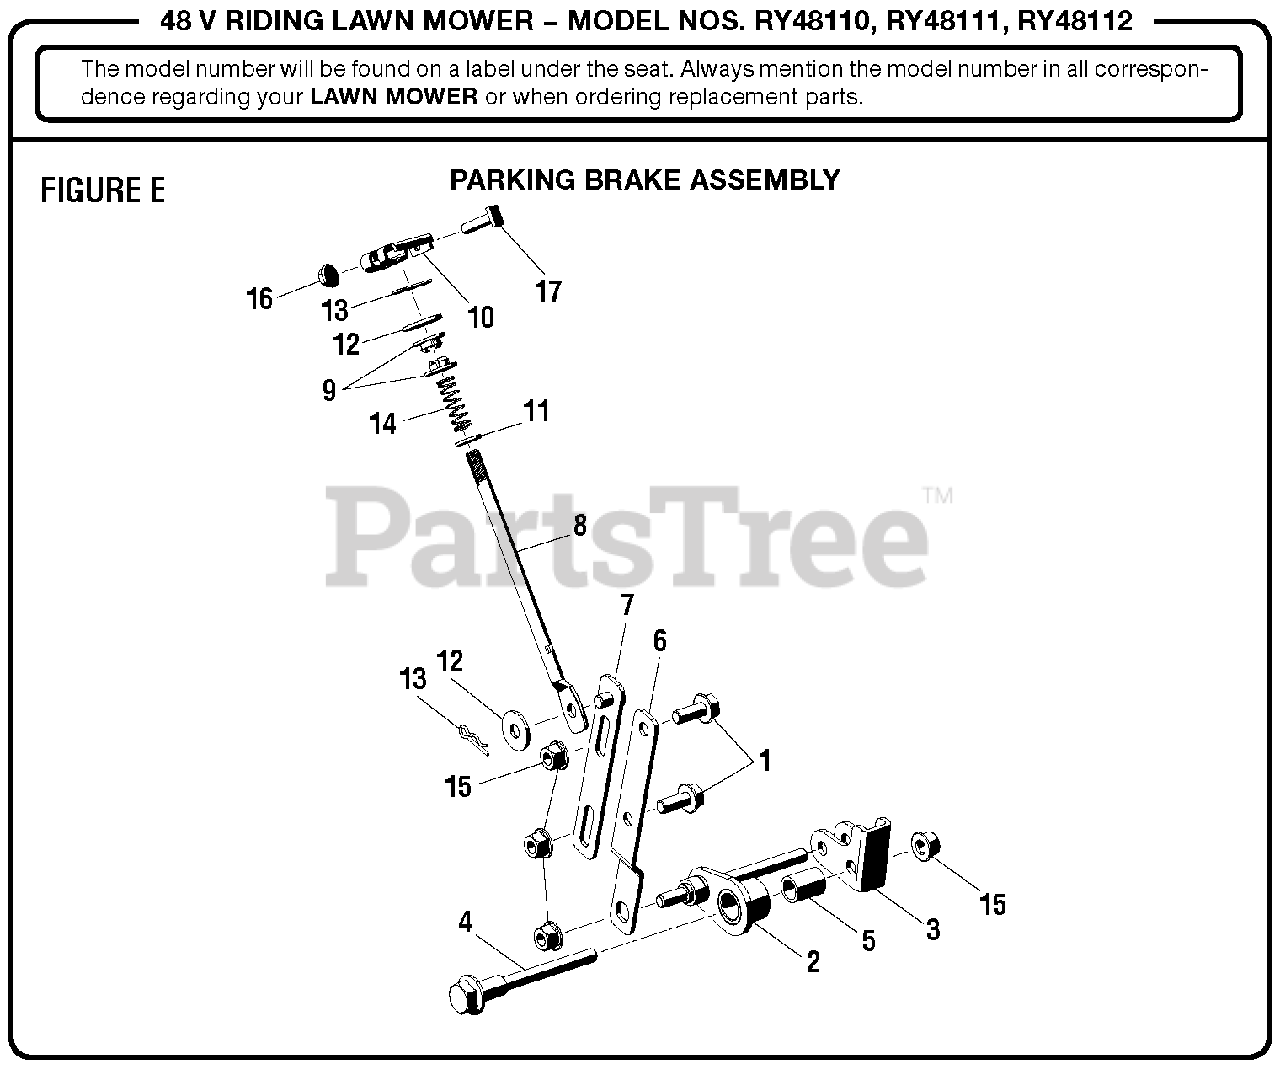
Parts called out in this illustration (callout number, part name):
1	Flange Bolt (M8 x 20 mm, Hex Hd.)
2	Pivot Bracket
4	Center Step Bolt
5	Nylon Sleeve
6	Lower Connecting Plate
7	Upper Connecting Plate Assembly
8	Upper Rod
9	Spring Capture Bushing, Nylon
10	Lever Bracket
11	Washer (OD16 x ID8.4 x 1.6t)
12	Washer (OD24 x ID8.4 x 2t)
13	Cotter Pin (8 mm)
14	Compression Spring
15	Flange Nut (M8)
16	Flange Nut (M6 )
17	Screw (M6 x 22 mm, Rectangle Hd.)
